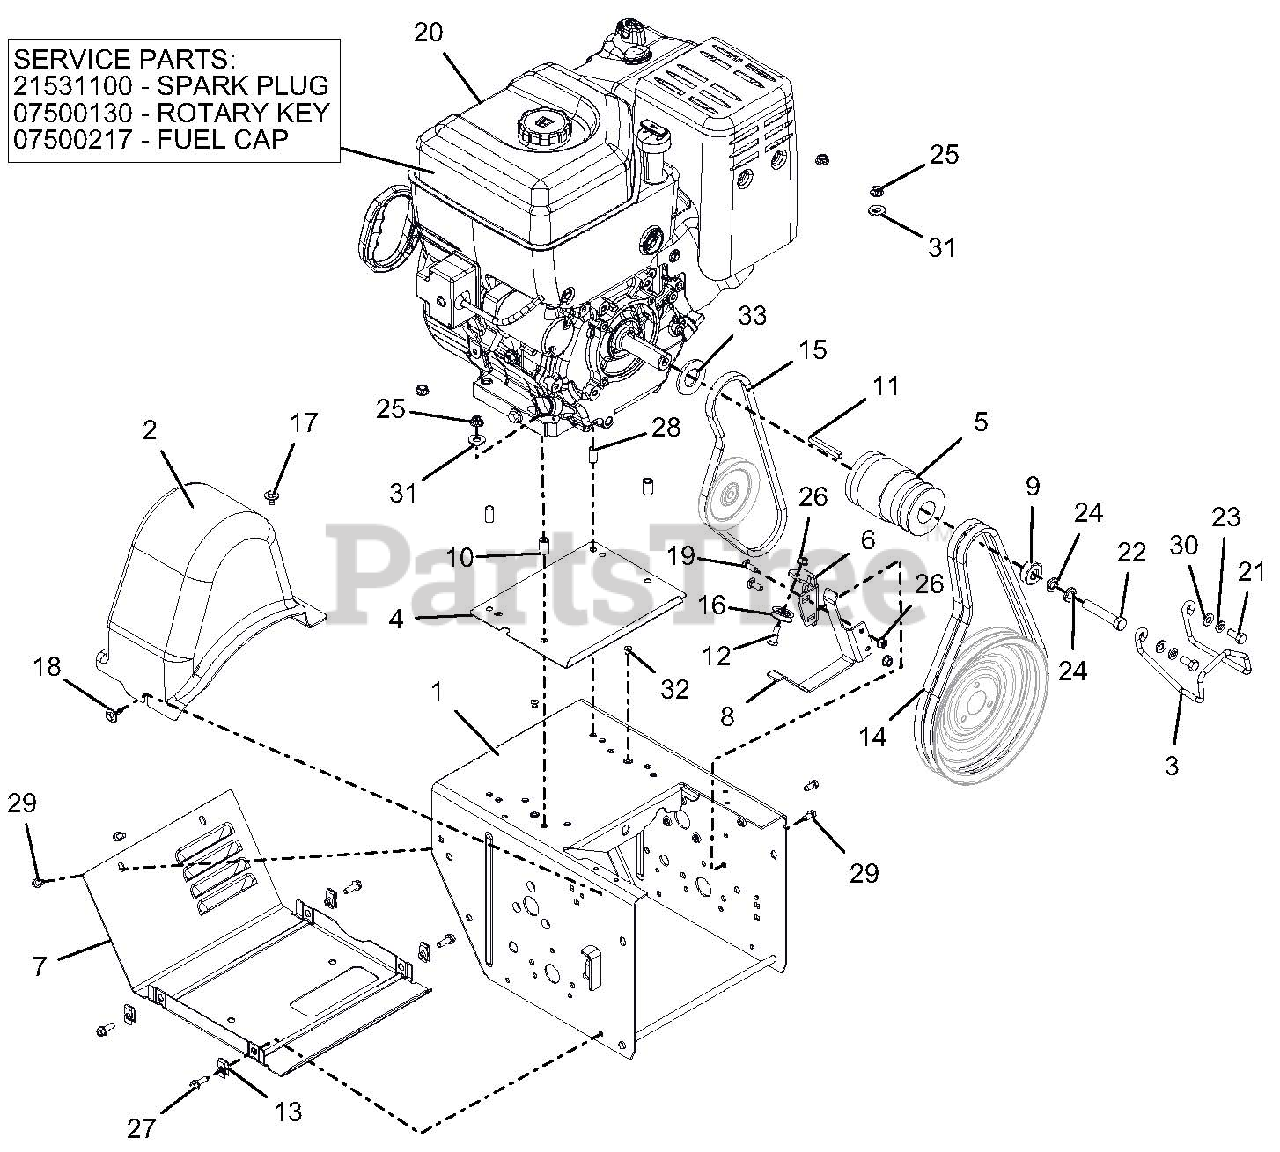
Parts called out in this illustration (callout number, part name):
1	PRO HYDRO FRAME, MAIN
2	COVER, BELT-LARGE PRO
3	FINGER, BELT
4	BAFFLE,ENGINE-PRO SERIES
5	SHEAVE, COMBO HYDRO TRACK 4L
6	BRACKET, CLUTCH CABLE
7	COVER, BOTTOM - VENTILATED
8	FINGER, BELT - FLAT
9	BSHG-SPACER .47X1.25X.50
10	BSHG-SLV .328X.50X.75
11	KEY .25X.25X2.25
12	BOLT, SHLDR-.375X.375X.25-20
13	NUT-RTNR .25-20X.56
14	V-BELT, HA-RAW EDGE (SET)
15	V-BELT, 4L-WRAPPED
16	PULLEY, CABLE
17	SCR-TAP .25-20X.50 LGHWH TR YZ
18	SCR-TAP .25-20X.5 CAPTIVE
19	@BLT-RDHDSQNK .25-20X.75 G5YZ
20	ENGINE, BRIGGS PF 2100, 120V
20	PLUG, SPARK 20HP B&S VANGUARD
20	KEY, IGNITION ROTARY B&S
20	CAP, FUEL - BRIGGS & STRATTON
21	BLT-HEX .31-24X.75 YWZC GR5
22	BLT-HEX .44-20X2.50 GR5 YWZC
23	WSHR-LK .312X.097 HVY YWZC
24	@WSHR-LK .44X.109 REG YWZC
25	@NUT-LK-CTR-FLG .31-18 YZ GR F
26	@NUT-LK-TOP-FLG .25-20 YWZC
27	BLT-HEX .25-20X.75 HWH YZ GR5
28	BSHG-SLV .325X.400X.795
29	SCR-TAP .25-20X.50 HWH TR YWZ
30	@WSHR-FL-STL.344X.688X.065YWZC
31	@WSHR-FL-STL.38X.875X.083 YWZC
32	RVT-POP .187 YZ
33	WSHR-FL-STL- 1.062X2.0X.134 YZ
